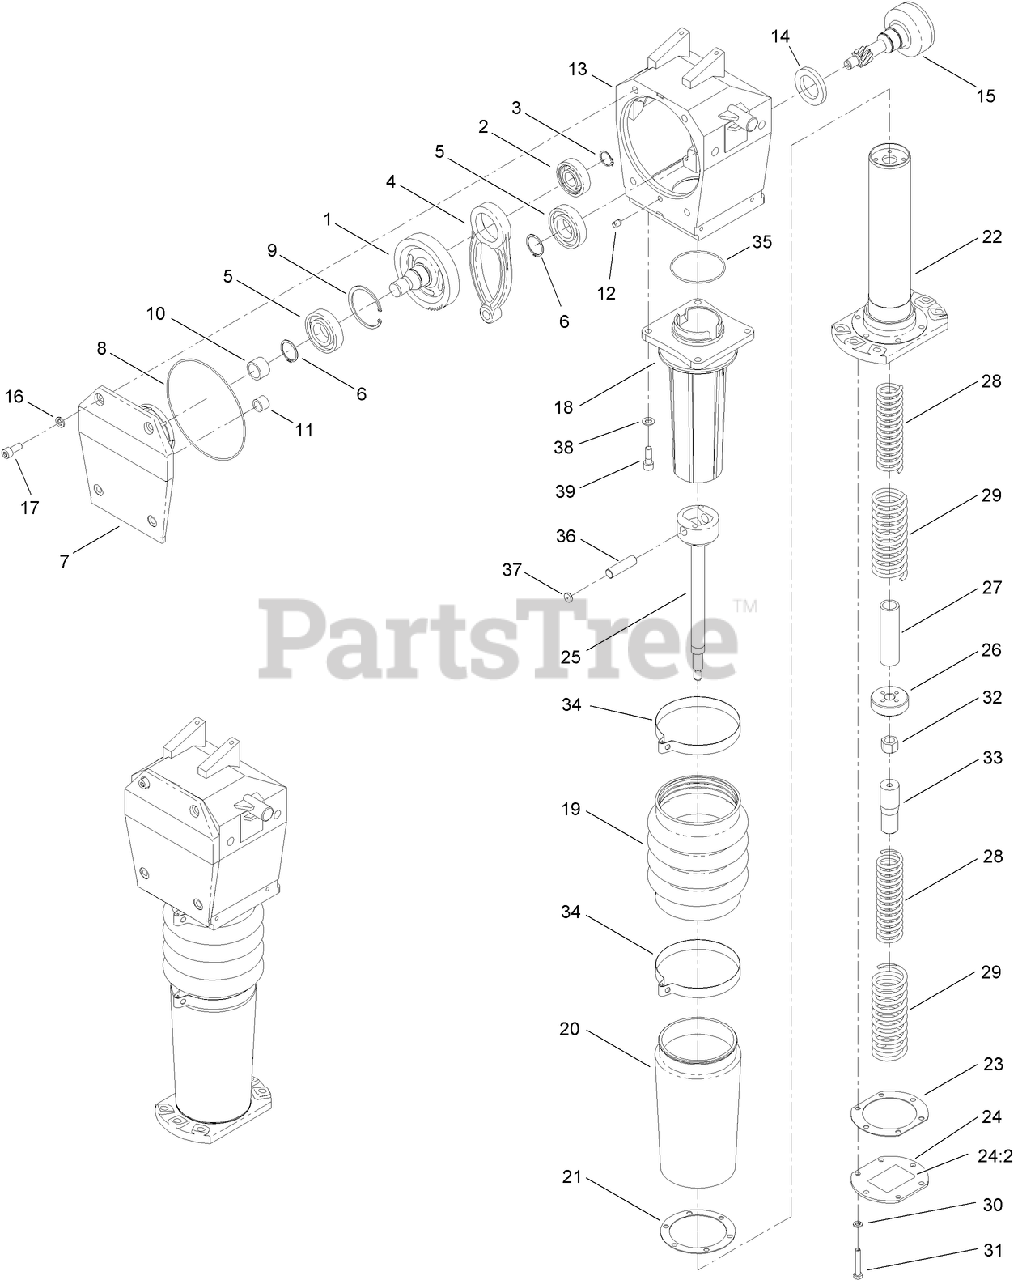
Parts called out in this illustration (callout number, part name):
1	GEAR-HELICAL
2	BEARING-BALL
3	RING-EXTERNAL
4	ROD-CONNECTING
5	BEARING-BALL
6	RING-SNAP, EXTERNAL
7	COVER-FRONT
8	O-RING
9	RING-INTERNAL
10	BEARING-NEEDLE
11	BEARING-NEEDLE
13	GEARCASE
14	SEAL-SHAFT
15	PINION
16	WASHER-LOCK, SPRING
17	SCREW-HSH
18	GUIDE-TUBE
19	BOOT-AWACK
20	COVER-HOUSING, SPRING
21	GASKET-HOUSING, SPRING COVER
22	HOUSING-SPRING
23	GASKET-COVER, SPRING
24	BOTTOM SPRING COVER ASM
24:2	DECAL-WARNING, SPRING
25	ROD-PISTON
26	PUCK-PISTON
27	SNUBBER-AXIAL, TOP
28	SPRING-COMPRESSION, INNER
29	SPRING-COMPRESSION, OUTER
30	WASHER-LOCK
31	Screw-HH
32	NUT-LOCK, NI
33	SNUBBER-AXIAL, LOWER
34	CLAMP-BOOT, STOMPER
35	O-RING
37	BUTTON-PIN, CAPTIVATOR
38	WASHER-FLAT
39	SCREW-HSH
